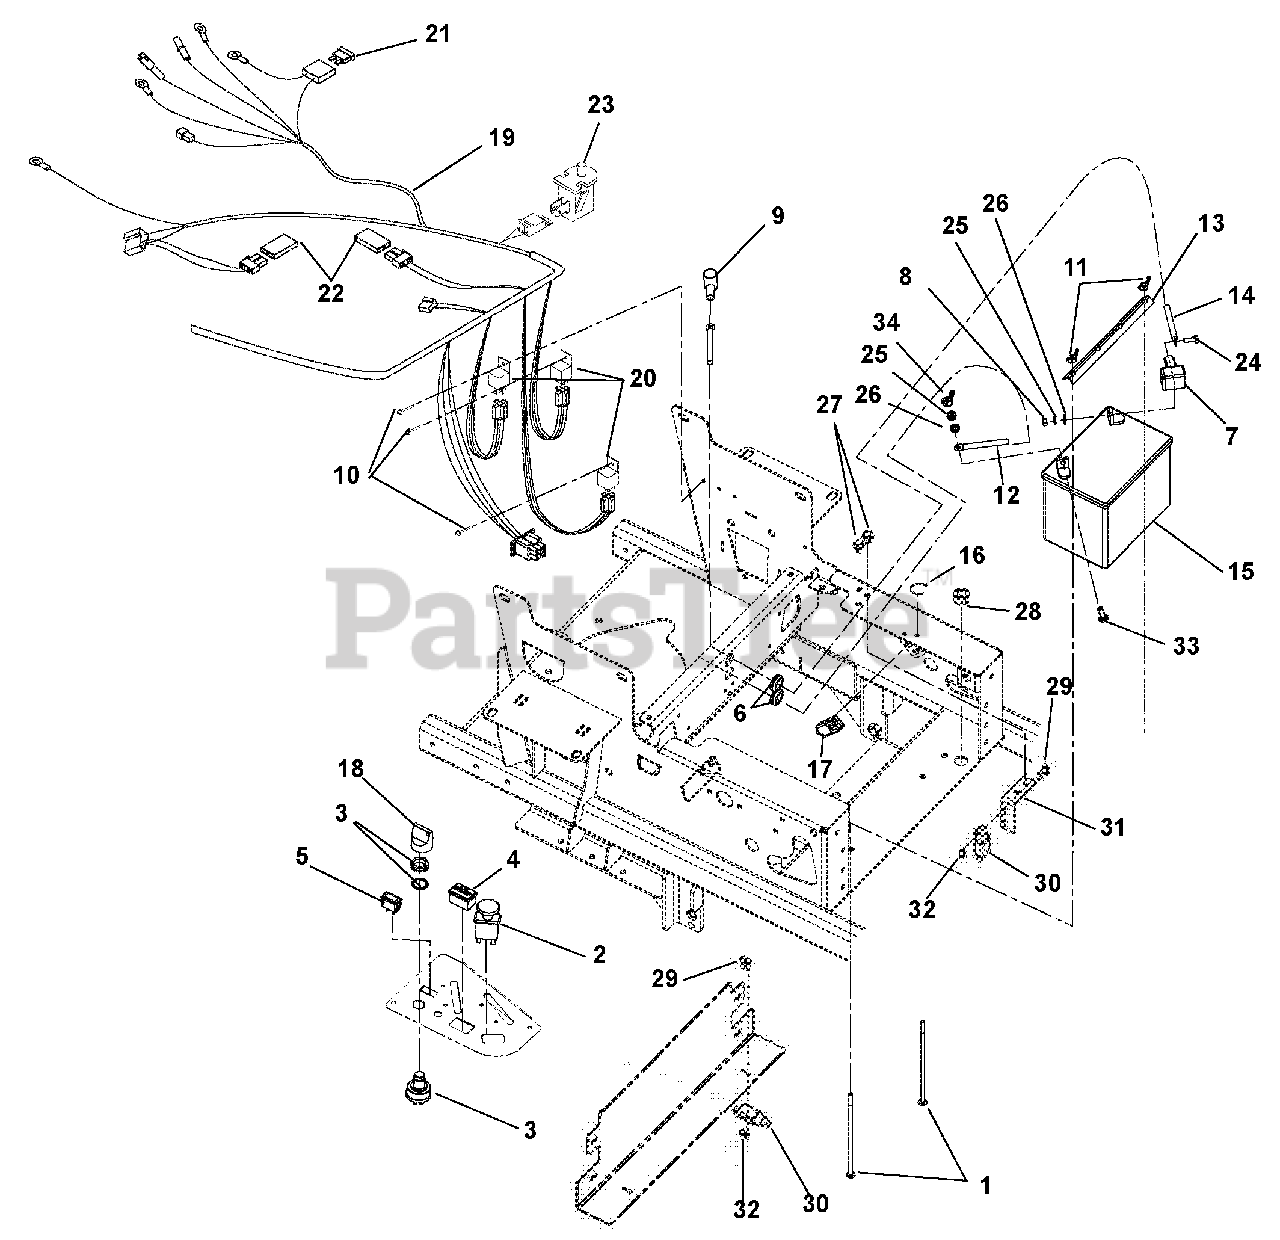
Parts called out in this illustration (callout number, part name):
1	Bolt, Round Head Square Neck .25-20 x 7.50
2	Switch, Clutch
3	Switch, Ignition
4	Hour Meter w/Maintenance
5	Light, Indicator
6	Bushing, Panel Snap .687 x .875 x .56
7	Insulator
8	Nut, Hex .25-20
9	Battery Terminal Boot, Red
10	Rivet, .25 Nylon Panel
11	Nut, Locking Wing .250-20
12	Ground Cable .31 x 22.00 x .31
13	Hold Down
14	Cable, Positive Battery 26.00"
15	Exide Battery, Sealed Maintenance Free U1-250
16	Cable Tie
17	Switch, Snap In-N.O./N.O.
18	Key, with Shield
19	Harness, Pro-Turn 100 Wire
20	Relay, Sealed w/Diode
21	Fuse, 30 AMP.
22	Diode, Connector Shell
23	Switch, Snap Mounting (N.O.)
24	Bolt, Hex .25-20 x .75
25	Washer, Locking .25 x .062 Regular
26	Washer, Flat-STL .281 x .62 x .065
27	Screw, Tapping .31-18 x .50 Hex Washer Head
28	Bushing, Panel Snap .687 x .875 x .56
29	Screw, Machine 10-24 x .75 Hex Washer Head
30	Switch, Single Pole (N.O.) with Cover
31	Mount, Switch
32	Nut, Locking-Nylon 10-24 with Insert
33	Bolt, Round Head Square Neck .25-20 x .75 YZ
34	Nut, Wing .25-20 YZ
